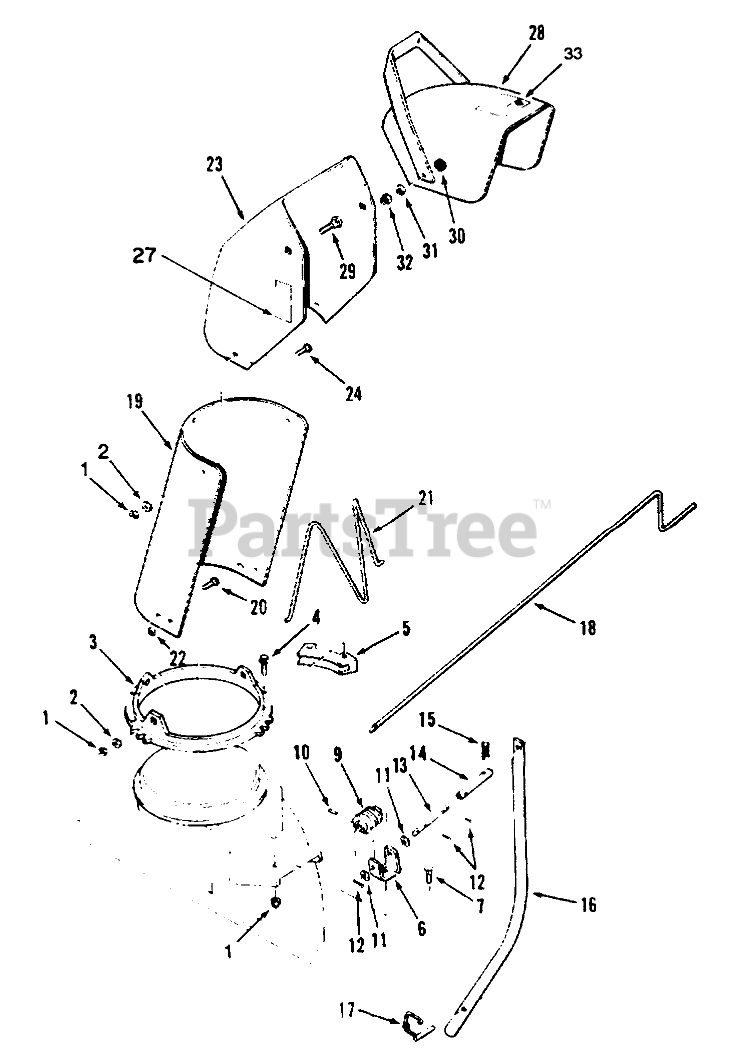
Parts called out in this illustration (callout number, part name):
1	NUT-LOCK, NI
2	WASHER-FLAT
3	Screw
4	SCREW-SPECIAL
5	RETAINER-CHUTE
6	WORM BRKT B
7	BOLT-CARR
9	GEAR-WORM, CHUTE
10	Pin-Roll
11	WASHER-FLAT
12	PIN-COTTER
13	ROD-LOWER CHUTE CONT
14	COUPLING
15	Hairpin Cotter
16	TUBE-CRANK SUPPOR R
17	LOCKING PIN ASM
18	ROD-CHUTE CONTROL
19	Chute-Extender
20	SCREW-HH
21	WIRE-CHUTE
22	NUT-PUSH
23	Chute-Upper Discharge (Incl Ref. #27)
24	CARRIAGE BOLT -4
27	Decal-Danger
28	Defector W. A. (Incl. Ref. #33)
29	BOLT-CARR
30	WASHER-RUBBER
31	WASHER-BELLEVILLE
32	NUT-LOCK, NI
33	Decal-Danger
